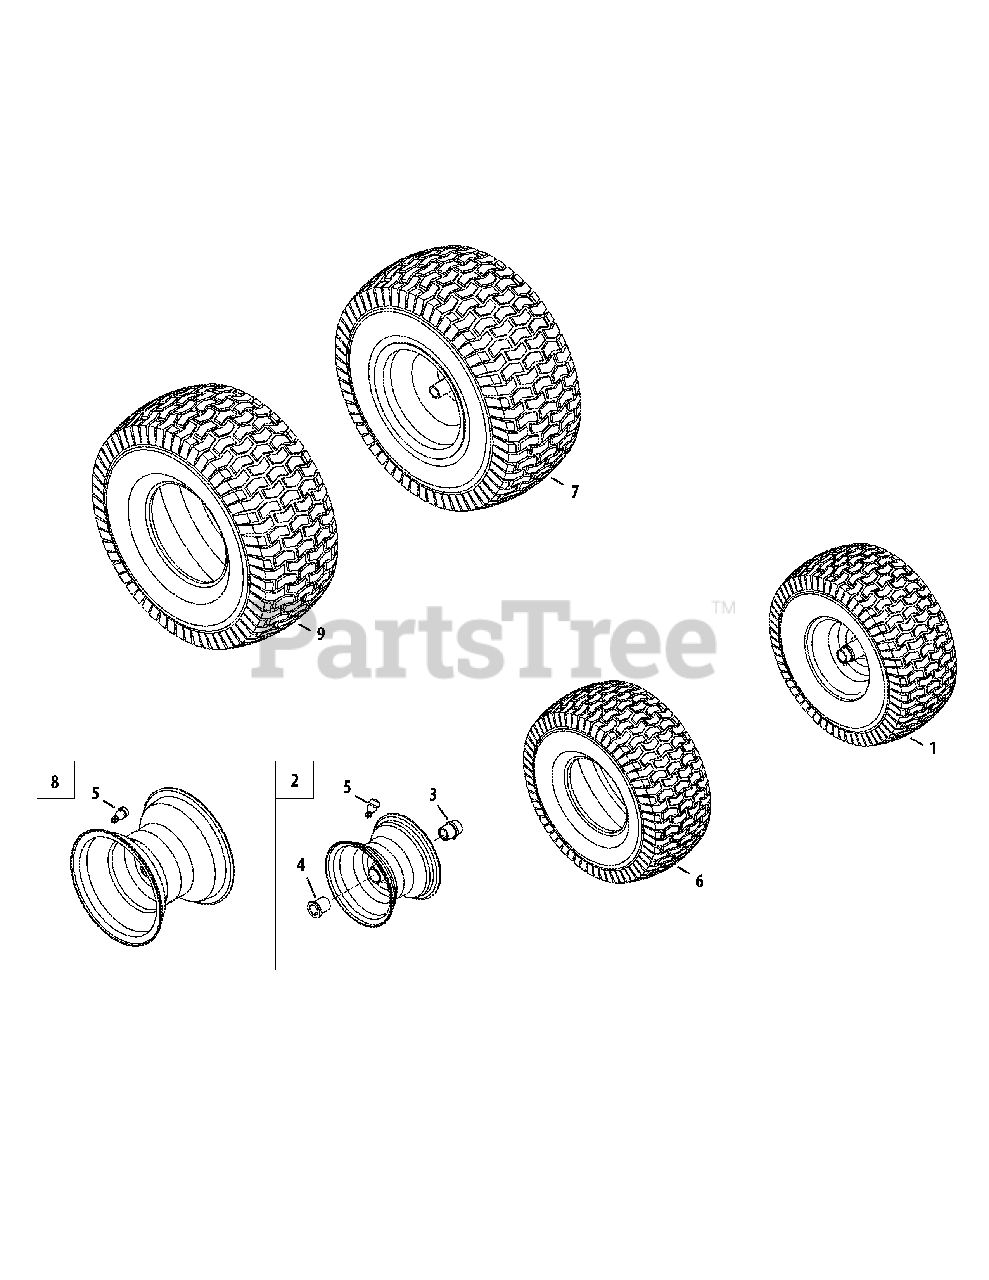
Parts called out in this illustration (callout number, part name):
1	Wheel Ass'y Complete, 15 x 6 x 6
2	Rim Ass'y 6.0 x 4.5 (w/plastic brg)
3	Flange Bearing .760 ID w/fitting
4	Flange Bearing .760 x 1.0 x 1.20
6	Tire 15 x 6 x 6 Square Shoulder
7	Wheel Ass'y Complete, 20 x 8 x 8
8	Rim Ass'y, 8.0 x 7.0 x .75
9	Tire 20 x 8 x 8 Square Shoulder
